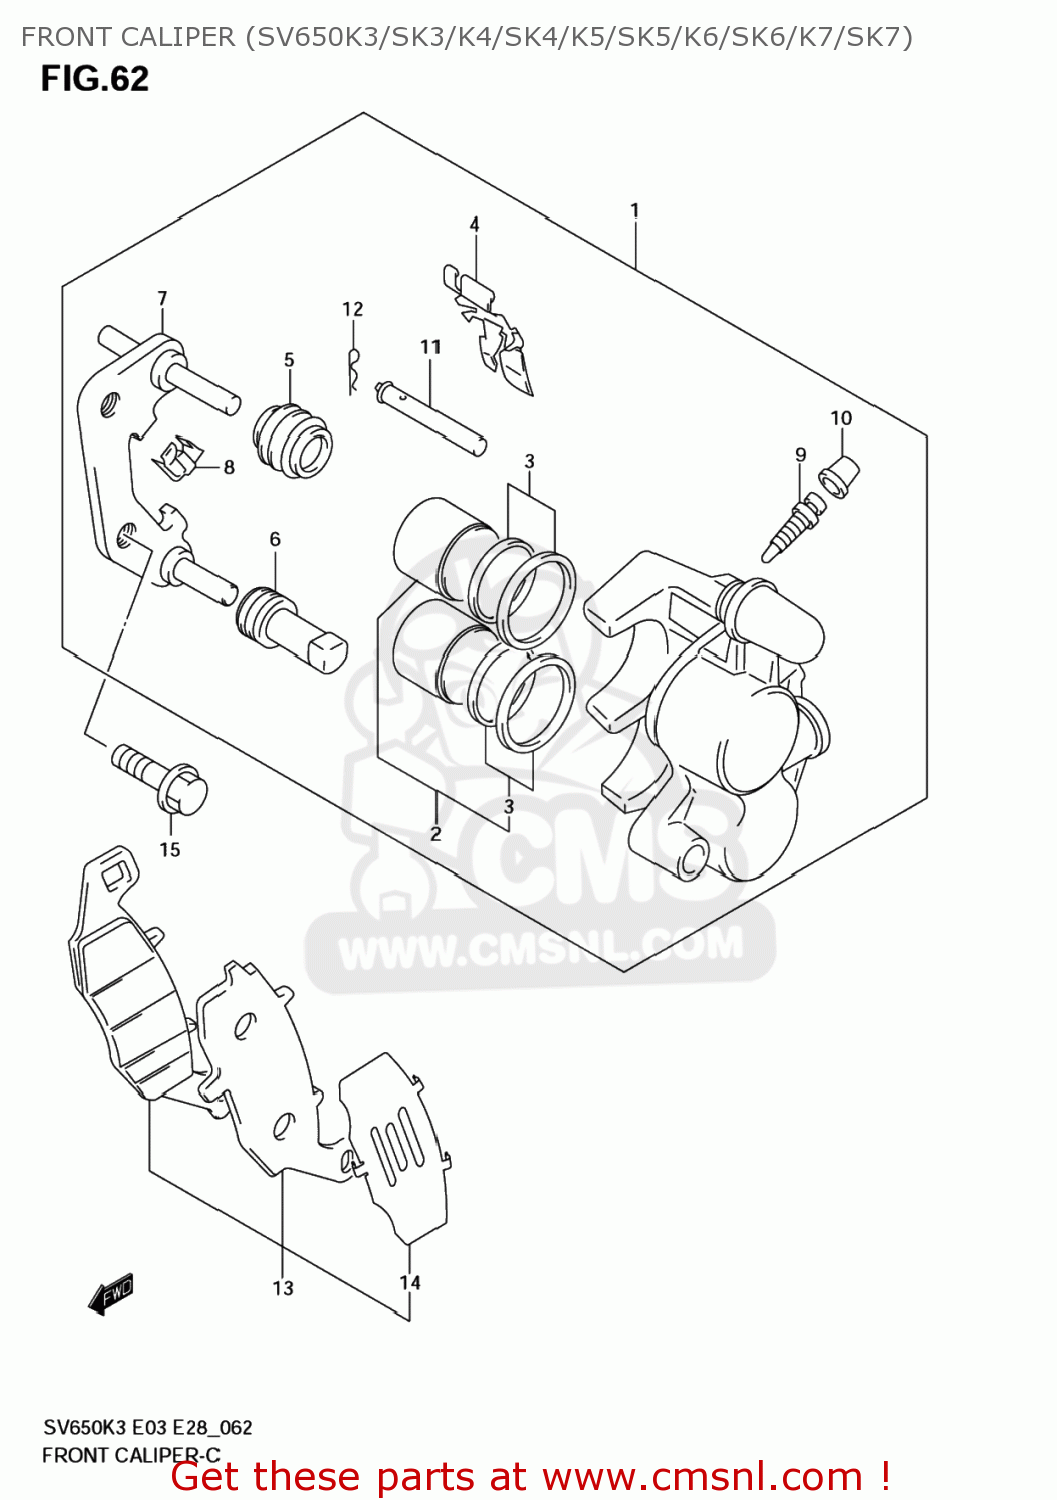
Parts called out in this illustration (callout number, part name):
1	CALIPER ASSY, FRONT RH
2	PISTON SET
3	SEAL SET,PISTON
4	SPRING,PAD,R
5	BOOT,AXLE
6	INSULATOR,AXLE
7	CARRIER,CALIPER,R
8	GUIDE,PAD
9	BLEEDER
10	CAP,BLEEDER PLUG
11	PIN,PAD
12	CLIP,PAD PIN
13	PAD & SHIM SET (NAS)
14	SHIM,PAD
15	BOLT
